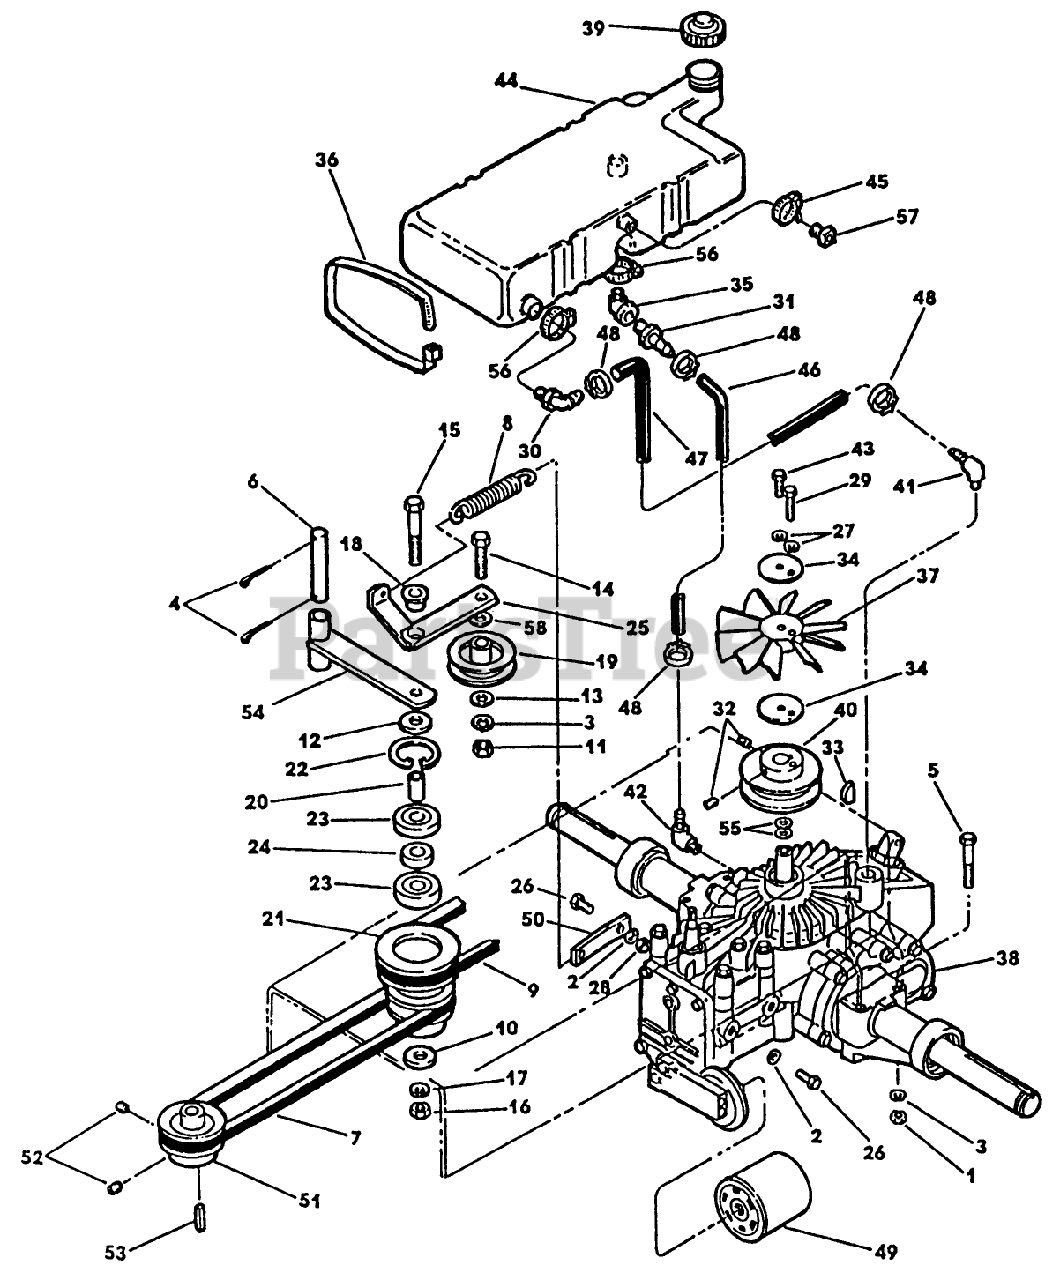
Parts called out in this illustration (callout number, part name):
24	SPACER, BEARING
26	SCREW - HEX
34	FRAME MTG WASHER LB
39	CAP,TANK
52	SET SCREW
54	IDLER ARM WELDMT *B
56	CLAMP-HOSE
